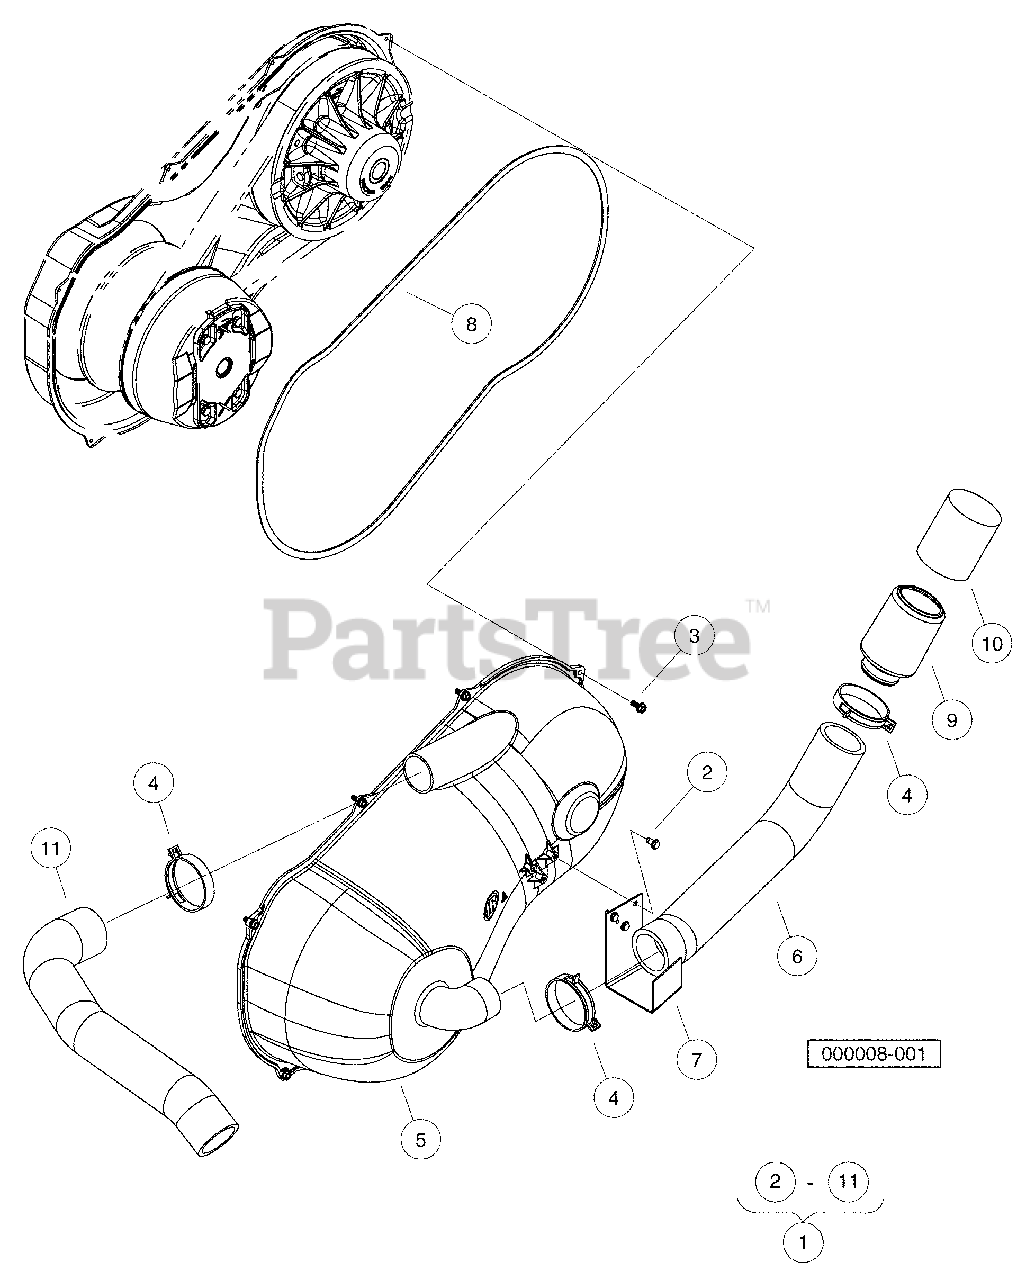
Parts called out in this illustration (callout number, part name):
1	Kit, Sealed CVT Cover
2	Screw, 1/4-15 X 1.50 Hi-lo Hex
3	Screw, M6 X 16 Tt Hx Fl Hd
4	Clamp, Hose, Ctb 64mm
5	Cover, CVT Outer
6	Hose, Inlet, Cover, CVT
7	Bracket, Inlet, Cover, CVT
8	Gasket, Cover, CVT
9	Cap, Inlet, Cover, CVT
10	Filter, Inlet, Cover, CVT
11	Hose, Outlet, Cvt
